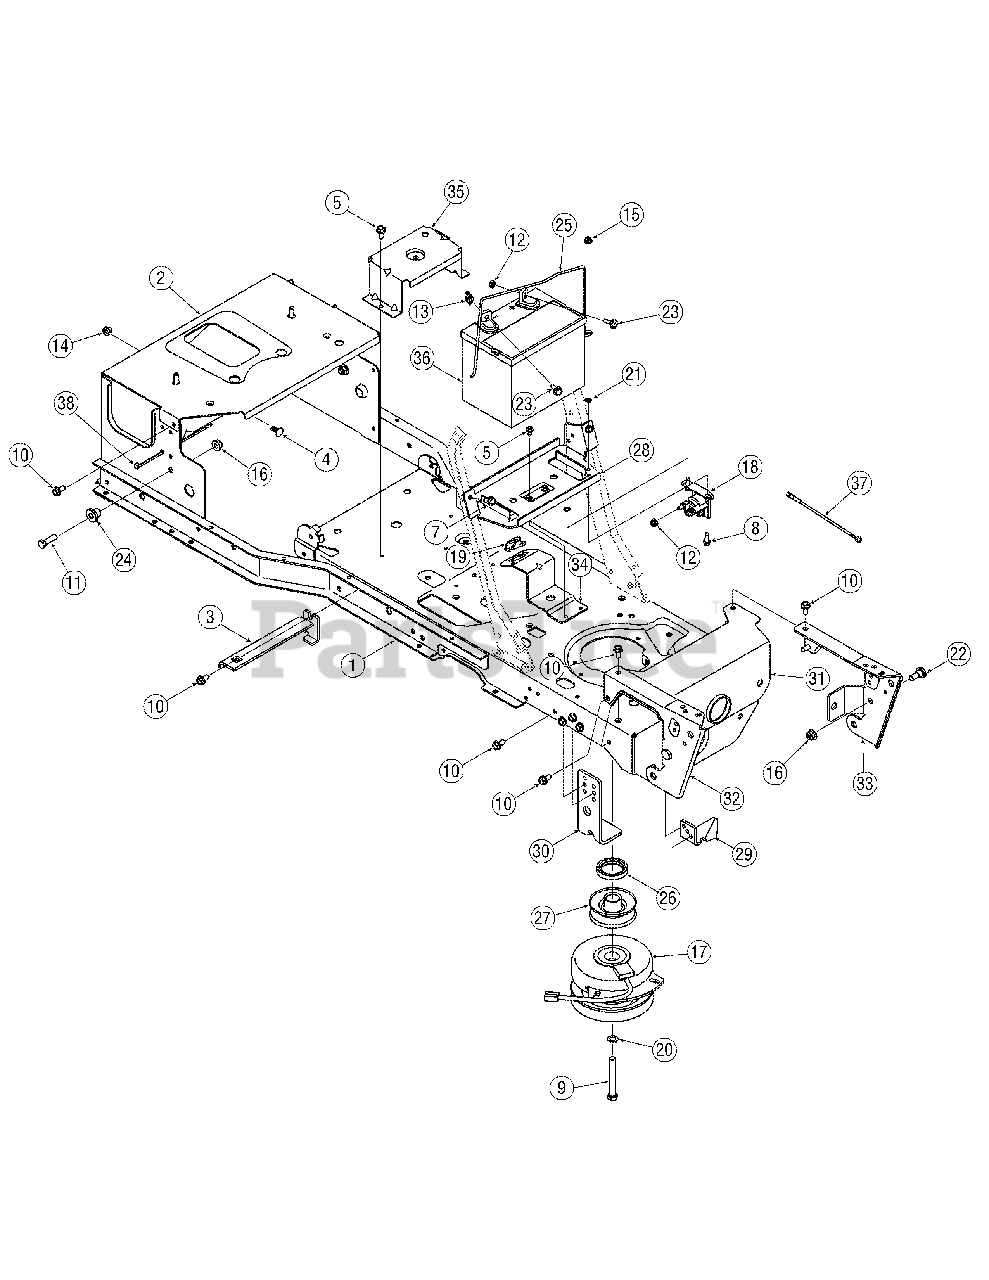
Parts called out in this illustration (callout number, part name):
5	Screw, Hex Wash. Hd. Tapp, 1/4-20 x .5
7	Screw, Hex Wash. Hd. Tapp, 5/16-12 x .75
8	Screw, Hex Wash. Hd. Tapp, 1/4-20 x .75
9	Screw, Hex Cap Lock, 7/16-20 x 3.5 Gr5
10	Screw, TT, 5/16-18 x .75
11	Screw, Hex Cap, 3/8-16 x 1.25 Gr5
12	Nut, Hex Sems, 1/4-20
13	Nut, Wing, 1/4-20
14	Nut, Hex Flange Insert Lock, 5/16-18
15	Nut, Hex Flange Insert Lock, 1/4-20 GrF
16	Nut, Hex Flange Insert Lock, 3/8-16 GrF
17	Clutch, Electric PTO
18	Solenoid, Start
19	Bushing, Steering Shaft
20	Washer, Lock, 7/16
21	Washer, External Lock, 1/4
22	Bolt, Shoulder, .496 x .336:3/8-16
23	Screw, Shoulder, .25 x .15:1/4-20
24	Screw, Shoulder, .38 x 1.0 x .7
26	Spacer, 1.37 x 1.00 x .25
27	Pulley, Engine
37	Wire, Ground Jumper
38	Cable Tie
